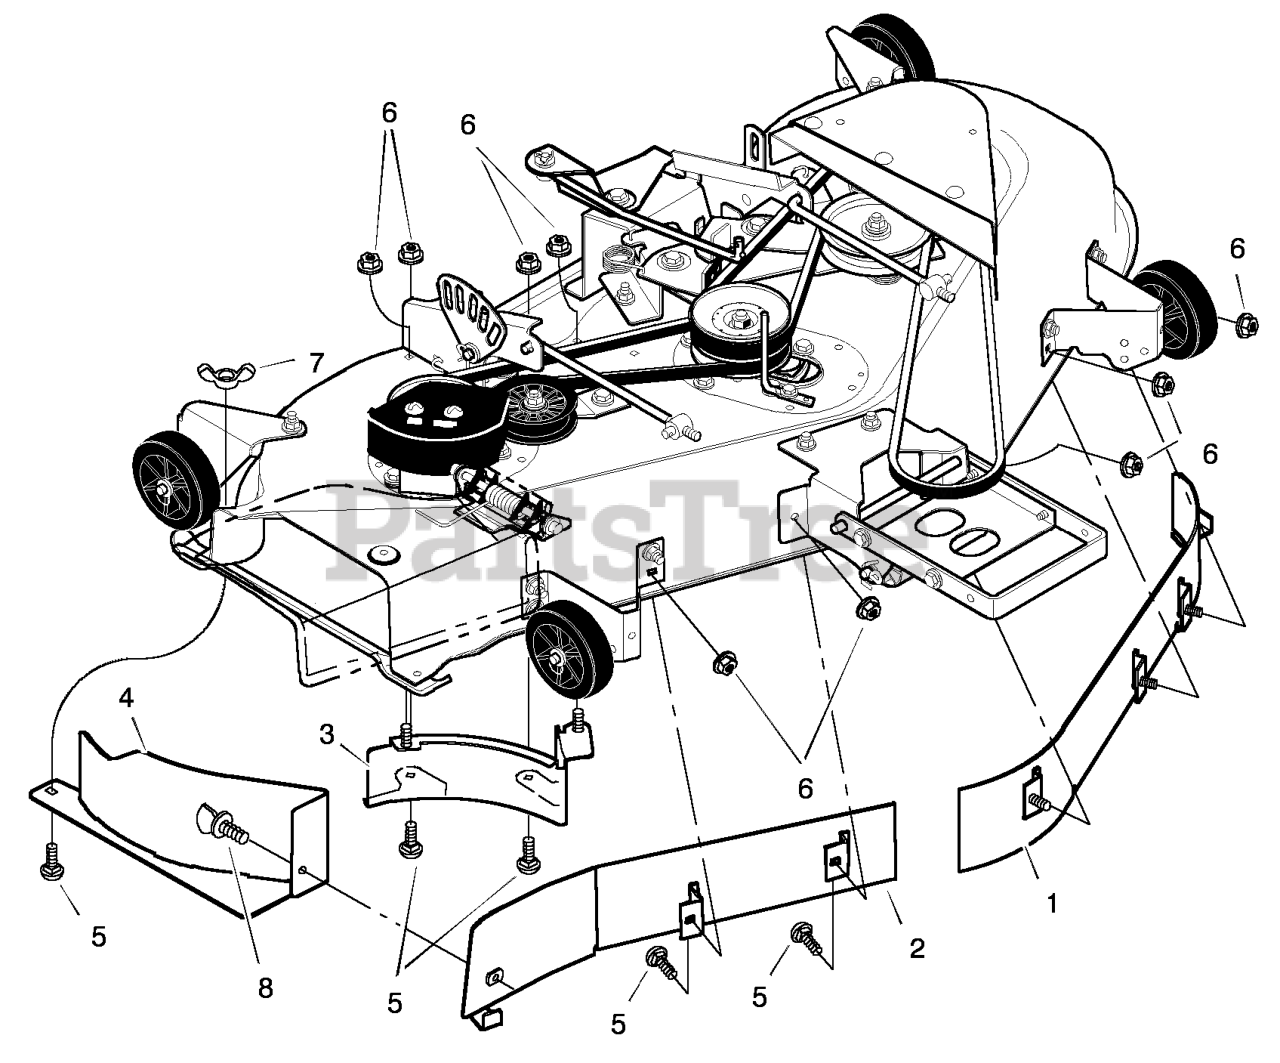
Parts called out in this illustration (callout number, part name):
1	Baffle, Left
2	Baffle, Right
3	Baffle Assembly, Rear
4	Plate, Mulcher
5	Bolt, Carriage
6	Nut, Flange
7	Wingnut
8	Screw, Thumb
